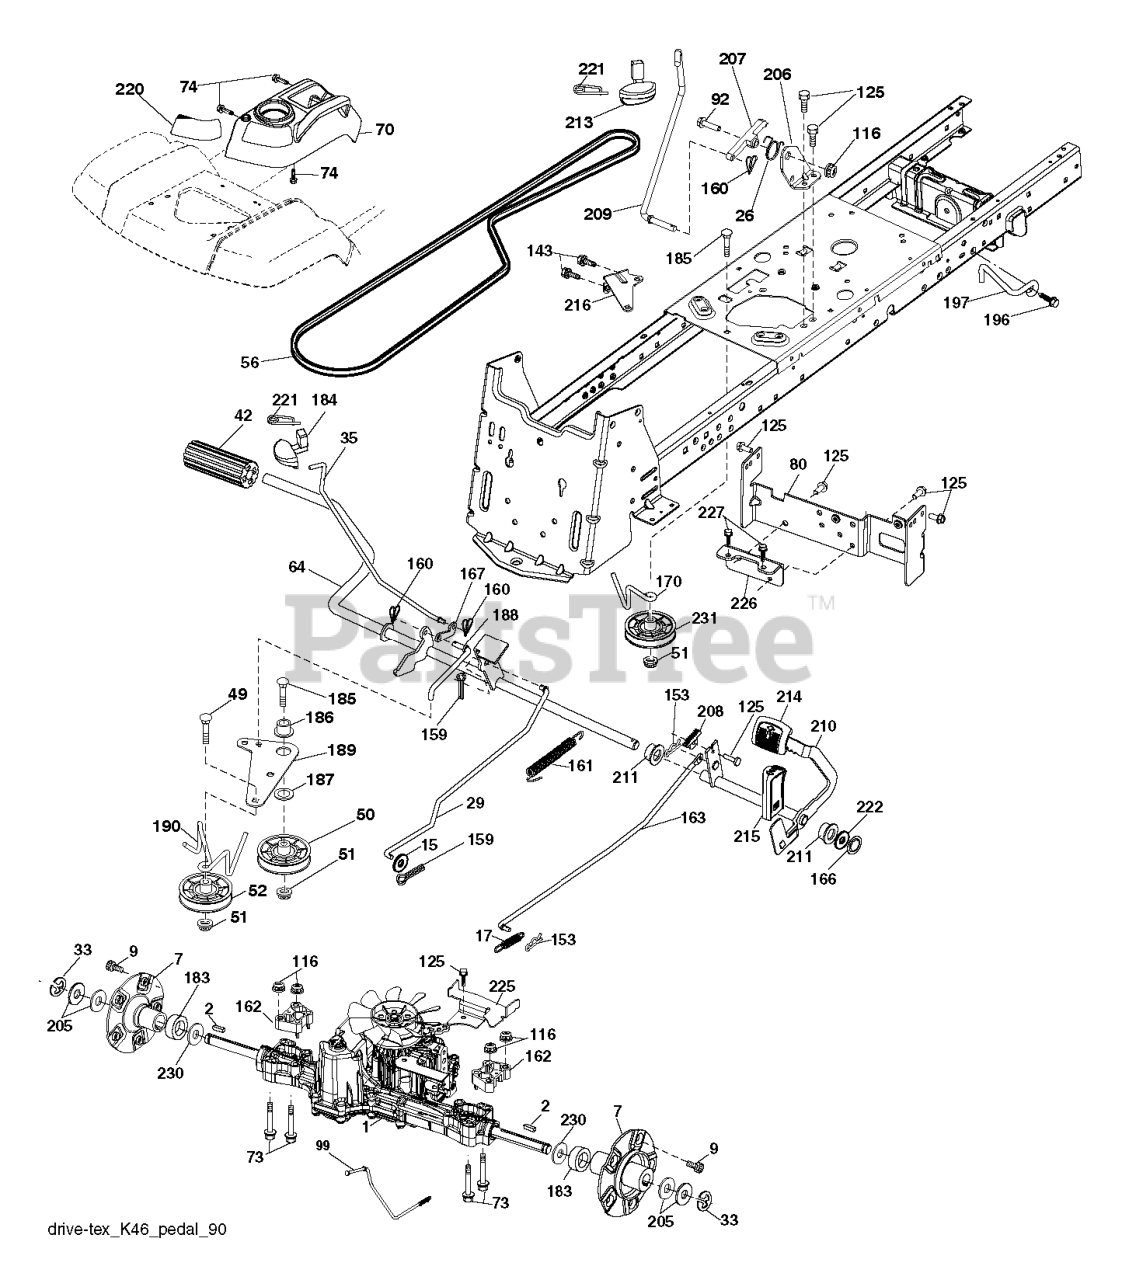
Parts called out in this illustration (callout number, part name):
2	KEY.SQUARE.187X2.500
7	HUB.ASM.WHEEL.REAR.22"
15	WASHER
17	SPRING.BRAKE.K46.GREEN
26	SPRING.RETURN.CRUISE
29	ROD.BRAKE.K46
35	ROD .BRAKE. PARKING. GT. HUSQ.
42	PEDAL COVER T
50	IDLER.FLAT.910.OFFSET
51	NUT LOCK FLG 3/8-16 UNC
52	IDLER.V-GROOVE.910.OFFSET
56	V-BELT.MOWER.92.40.42/K46
64	SHAFT.ASM.PEDAL.BRK.CNTR
70	CONSOLE.ASM.RH.GT.FC.HUSQ
73	BOLT.HEX.FLNG.5/16-18X3.75
74	SCREW.HI-LO.CONSOLE
80	STRAP.TORQUE.K46.K57R.TT
92	BOLT
99	ROD.SPRING.BYPASS.K46.TEX.GT
116	NUT LOCK HEX FLANGE 5/16-18
125	SCREW
143	Screw 5/16-18 x 1/2 Hex, Self Tapping 5/16-18 x 1/2
153	RETAINER M
159	COTTER PIN
160	RETAINER CLIP
161	SPRING, RETURN LT
162	SPACER.TRANSAXLE.18&22
163	ROD.CONTROL.K57R.K46
166	NUT.PUSH.625
167	LATCH.BRAKE.SPRING
170	KEEPER.CENTER SPAN.1.688
183	SPACER.SPLIT.800X.350
184	RB HANDLE.PARKG.BRK.HUS/PRED
186	SPACER.RETAINER
187	WASHER 12/32X2X10GA
188	RP.LINK.CLUTCH.GROUND.DRIVE
189	BELLCRANK.GROUND.DRIVE.TEX.
190	KEEPER.BELLCRANK.DRIVE
196	SCREW 3/8-16X1
197	BRKT.ANIT-ROTATION.CLUTCH
206	BRKT.MOUNT.LATCH.CRUIS
207	LATCH.CONTROL.CRUISE
208	GEAR.SECTOR.CONTROL.CR
209	ROD.CONTROL.CRUISE.GT.
210	ROCKER.ASM.PEDAL.CONTR
211	BEARING.NYLON
213	KNOB.CONTROL.CRUSIE.HU
214	PEDAL.FORWARD.PAD.TEX
215	PEDAL.REVERSE.TEX.GT.4
216	BRACKET.PULLEY.IDLER.W/TEX
220	REFLECTOR.RH.TEX GT
221	RETAINER.SPRING.CLIP.H
222	WASHER 21/32 X 1-1/4 X 10 GA.
225	KEEPER.BELT.TRANSAXLE.K46
226	BRKT.MOUNT.TORQUE.K46.
227	SCREW.THDROL.5/16-18X3/4.TTY
230	WASHER.HARDENED
231	IDLER.V-GROOVE.1.688.OFFSET
